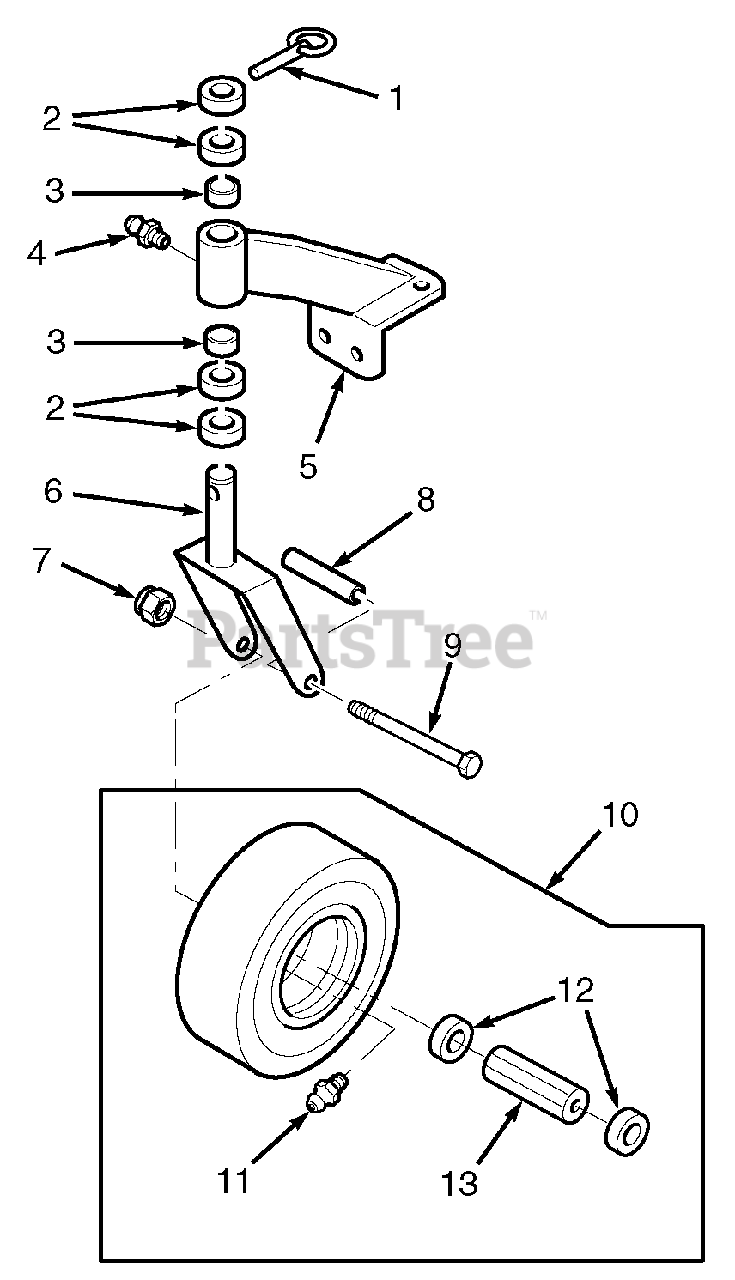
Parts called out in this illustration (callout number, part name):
1	Quick Pin
2	Spacer, Caster Yoke, 1/2" Long
3	Bronze Bearing
4	Grease Fitting
5	Support Assembly
6	Caster Yoke
7	Elastic Stop Nut, 1/2-13
8	Sleeve, Caster Wheel Bearing
9	Hex Hd. Bolt, 1/3-13 x 5-1/2"
10	Flat Free Tire Assy.
11	Grease Fitting, 45 Degree 1/4-28
12	Retainer, Bearing, Caster Wheel
13	Roller Bearing, Caster Wheel
